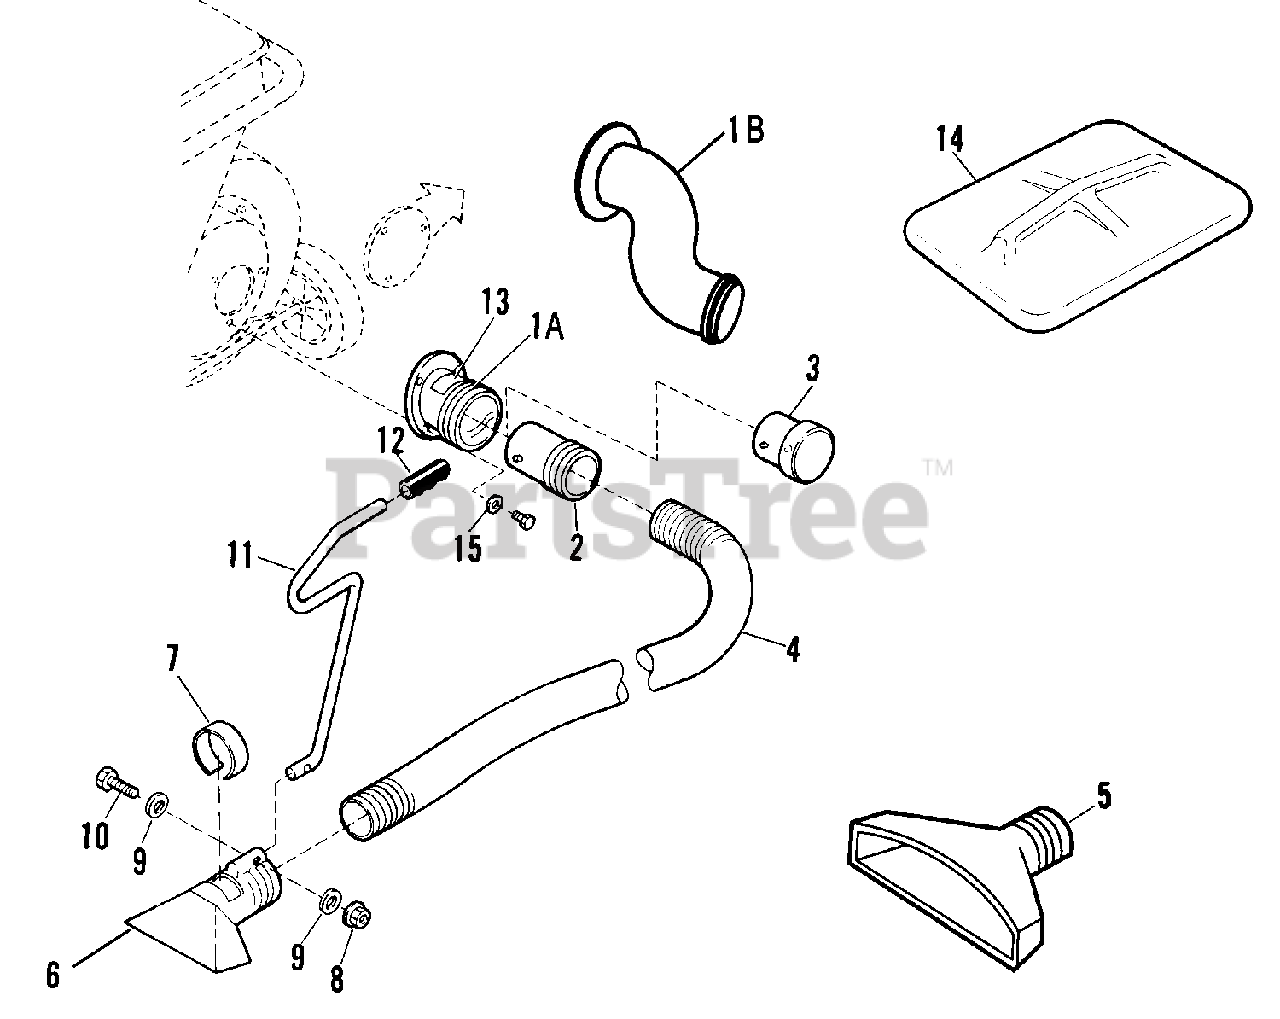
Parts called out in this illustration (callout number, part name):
1A	ADAPTER
1B	ADAPTER (European model only)
2	COUPLER
3	Plug
4	HOSE, 10" x 4" Dia.
5	LEAF TRAY
6	NOZZLE, w/Valve Ring
7	VALVE RING
8	NUT, 1/4-20
9	WASHER, 1/4
10	SCREW, 1/4-20 x 1 1/2
11	HANDLE
12	HANDLE GRIP
13	DECAL, Danger
14	HOPPER LID (Red)
15	WASHER, Flat
